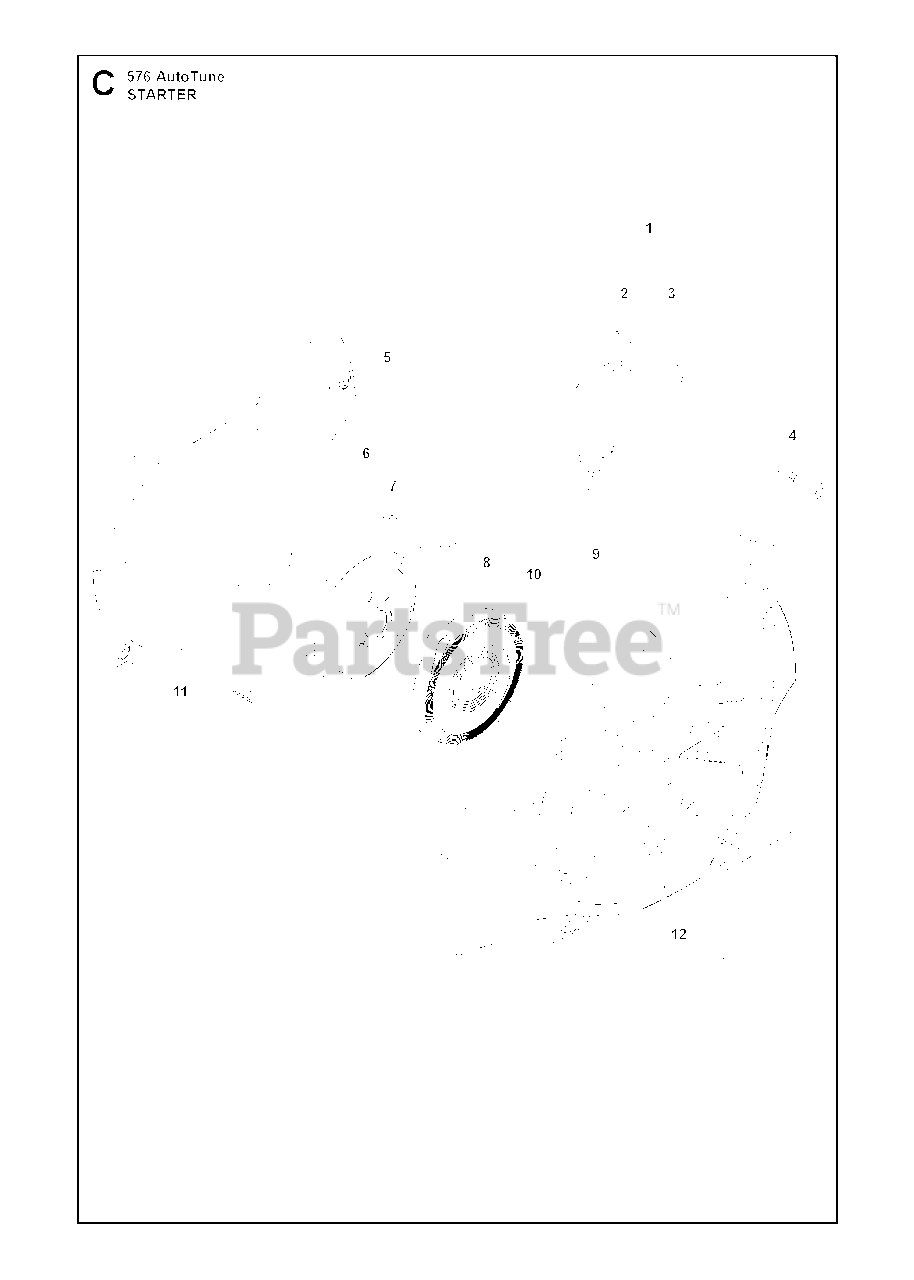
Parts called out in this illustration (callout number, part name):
1	STARTER ASSY
2	STARTER ROPE
3	HANDLE
4	SCREW
5	PLATE
6	STARTER PULLEY
7	SCREW
8	RP SPRING
9	SLEEVE
10	STARTER HOUSING
11	SCREW
12	LABEL
12	LABEL (576XPG AUTO TUNE)
